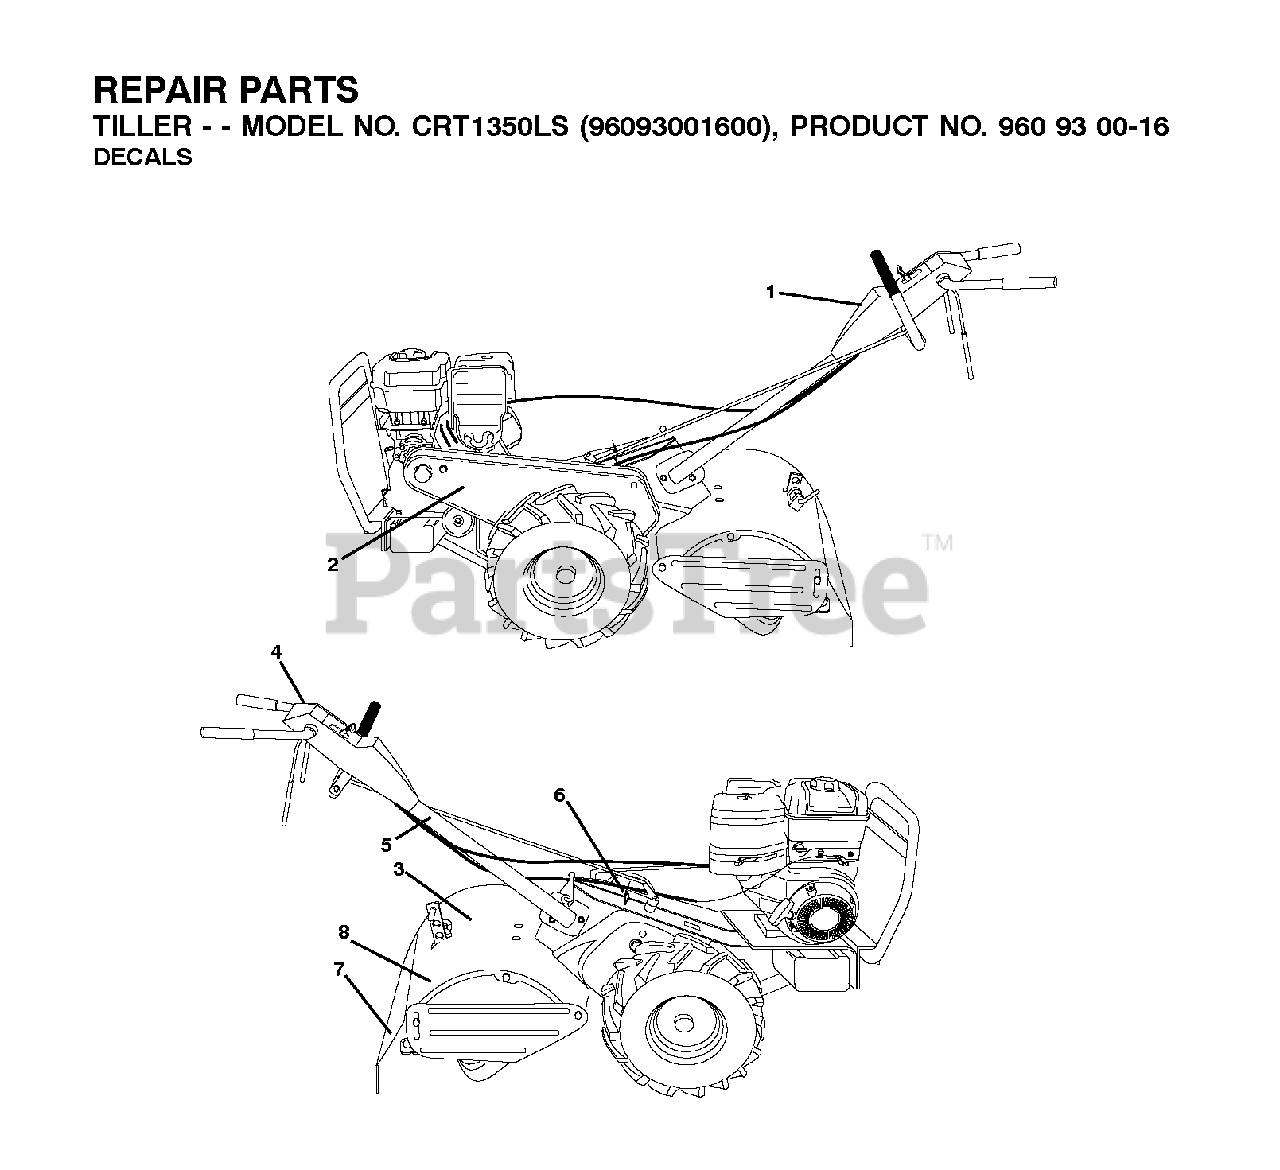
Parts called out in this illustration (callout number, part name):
1	Decal, Logo
2	RP.DECAL.BADGE.170MM.TEXTLOGO
3	Decal, Tine Shield
4	Decal, Console INS CRT
5	DECAL TI (2 2)
6	DECAL, SHIFT INDICATOR
7	DECAL TI
8	DECAL.WARNING.SHLD.ENG/FR
